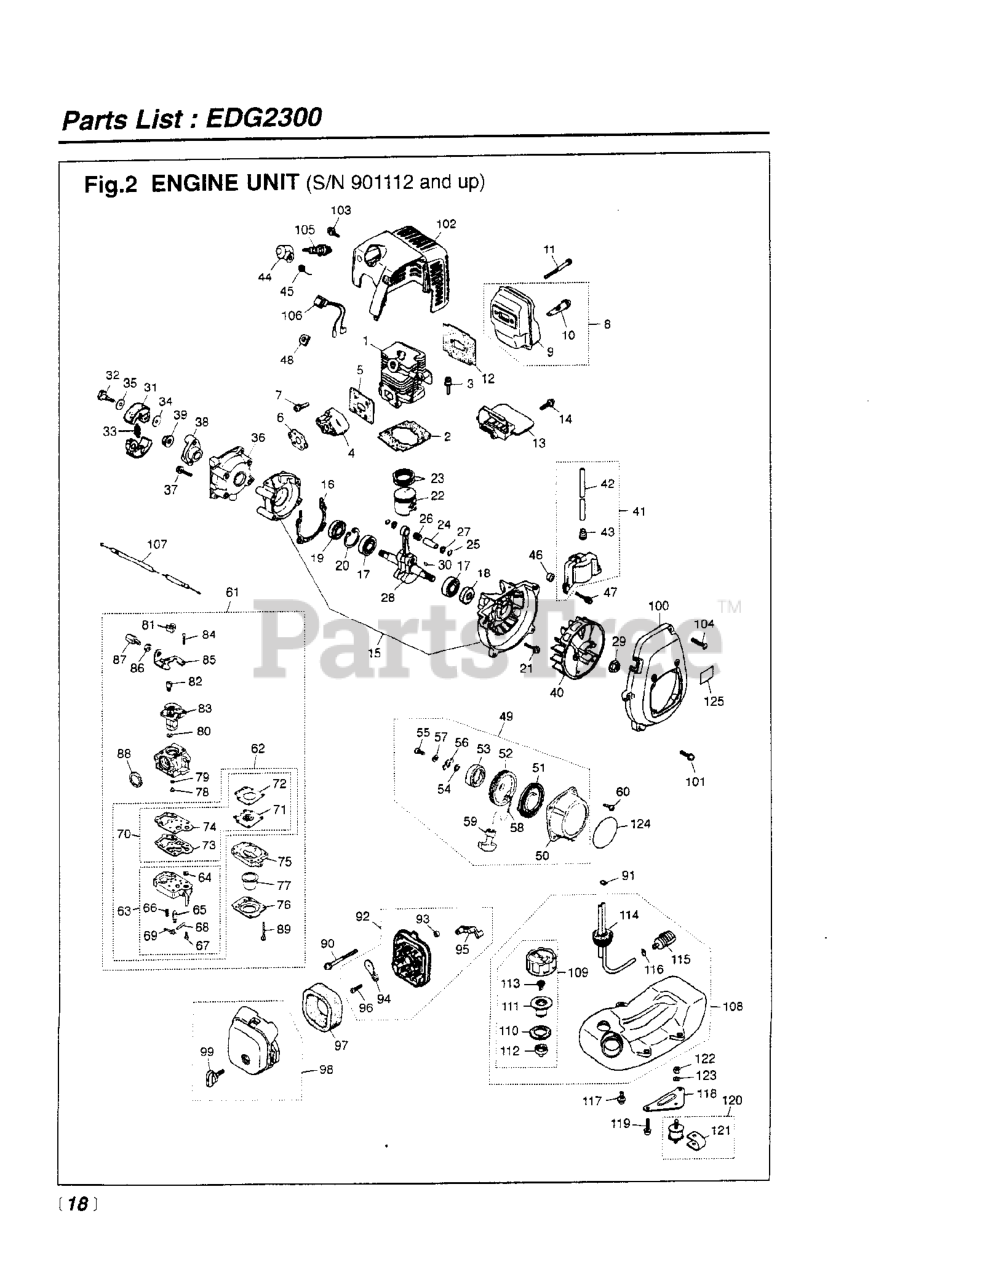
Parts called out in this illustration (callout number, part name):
1	CYLINDER
4	INSULATOR
8	MUFFLER ASSEMBLY
10	ARRESTER
11	BOLT, M5 x 50 (RPLS 125230550)
15	CRANKCASE-C
19	SEAL
23	RING
24	PIN.PISTON
28	CRANKSHAFT (RPLS 560042000)
29	NUT
30	KEY
39	NUT
41	COIL-A
43	CAP
46	SPACER
48	GROMMET
49	RECOIL-A
50	CASE, RECOIL
51	SPRING.SPIRAL
61	CARBURETOR WYJ-113-1
62	REBUILD KIT
63	CARBURETOR BODY
70	GASKET KIT
76	1OVER
80	RING
81	WASHER
82	SWIVEL
83	RedMax TBD
84	SCREW
85	BRACKET
86	NUT
87	ADJUSTER
88	RING PACKING
91	CLIP
92	BODY-A
94	PLATE.CHOKE
96	SCREW
98	COVER-A
100	COVER.FAN
108	TANK-A
111	HOLDER-A
114	PIPE COMPLETE
116	CLIP
120	JOINT COMP
123	WASHER, SPRING M4 x 1.3
